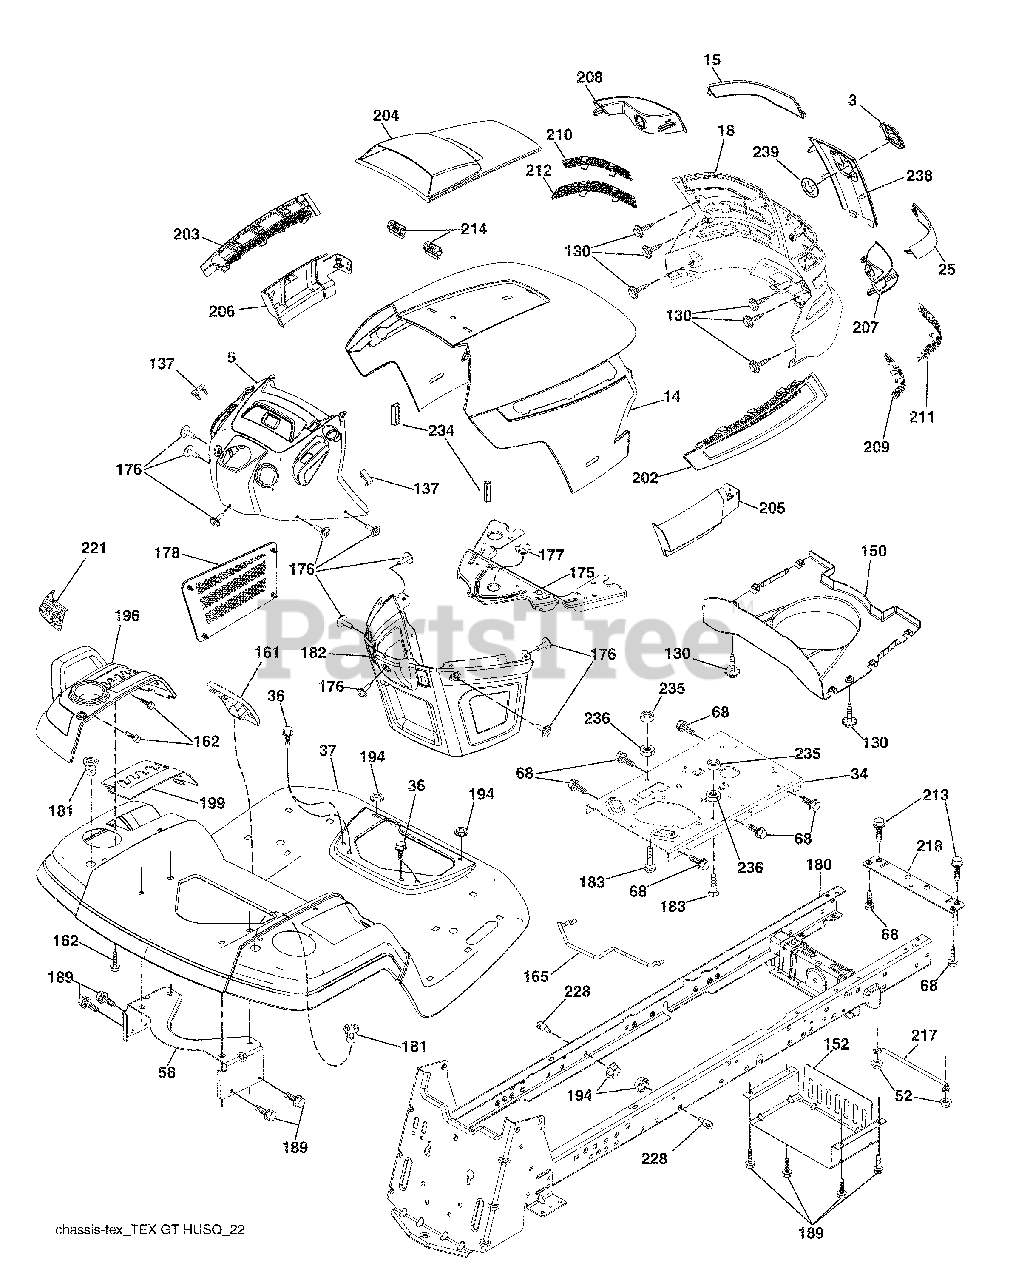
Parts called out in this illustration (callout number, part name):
3	Logo Husq
5	Dash
14	Hood
34	Plate Engine
36	Screw 5/16-18 x 3/4
37	Fender
52	Nut Lock 5/16-18
58	Bracket Fender
68	Screw 5/16-18 x 1/2
130	Screw #10 x 0.750
137	Bumper Dash
150	Duct Heat Hood
152	Shield Browning/Debris
161	Console Fuel Window
162	Screw Hex Wsh Hi-Lo 1/4 x 1/2
165	Bracket Support Tank
175	Crossmember
176	Screw 10-24 x 5/8 Rnd Qdrx
177	Bushing Steering
178	Cargo Asm. Net
180	Chassis
181	Bushing Mtg. Fender Crgo.
182	Dash Lower
183	Bolt 5/16-18 x 1-1/4
189	Screw 5/16-18 x 3/4
194	Nut Lock Hex Flange 5/16-18
196	Console Asm. Deck Lift
199	Plate Deck Lift
202	Vent Side Hood RH
203	Vent Side Hood LH
204	Vent Asm Hood Top
205	Skirt Hood Side RH
206	Skirt Hood Side LH
209	Insert Hex Top RH
210	Insert Hex Top LH
211	Insert Hex Bottom RH
212	Insert Hex Bottom LH
213	Bolt Hex Hd 5/16-18 unc x 3/4
214	Clip Retainer
217	Rod Pivot Hood
221	Reflector LH
228	Stud Fastner
234	Bumper Hood
235	Spacer Fender
236	Nut Lock 5/16-18 unc
